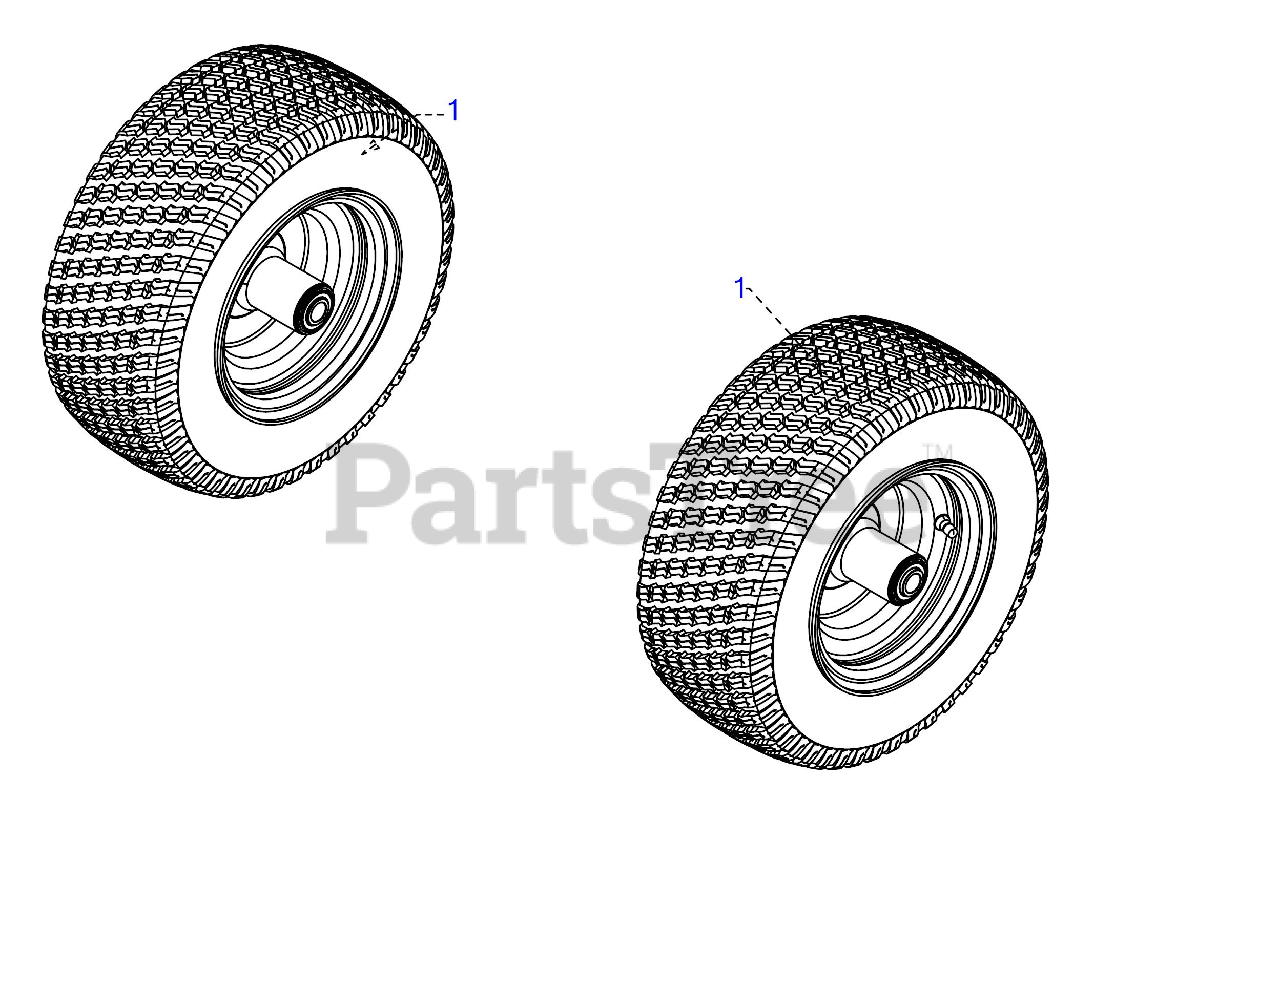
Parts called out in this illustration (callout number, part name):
1	TIRE (16x6.5-8)
1	FRONT WHEEL 16 x 6.5-8
1	SEALED BALL BEARING
